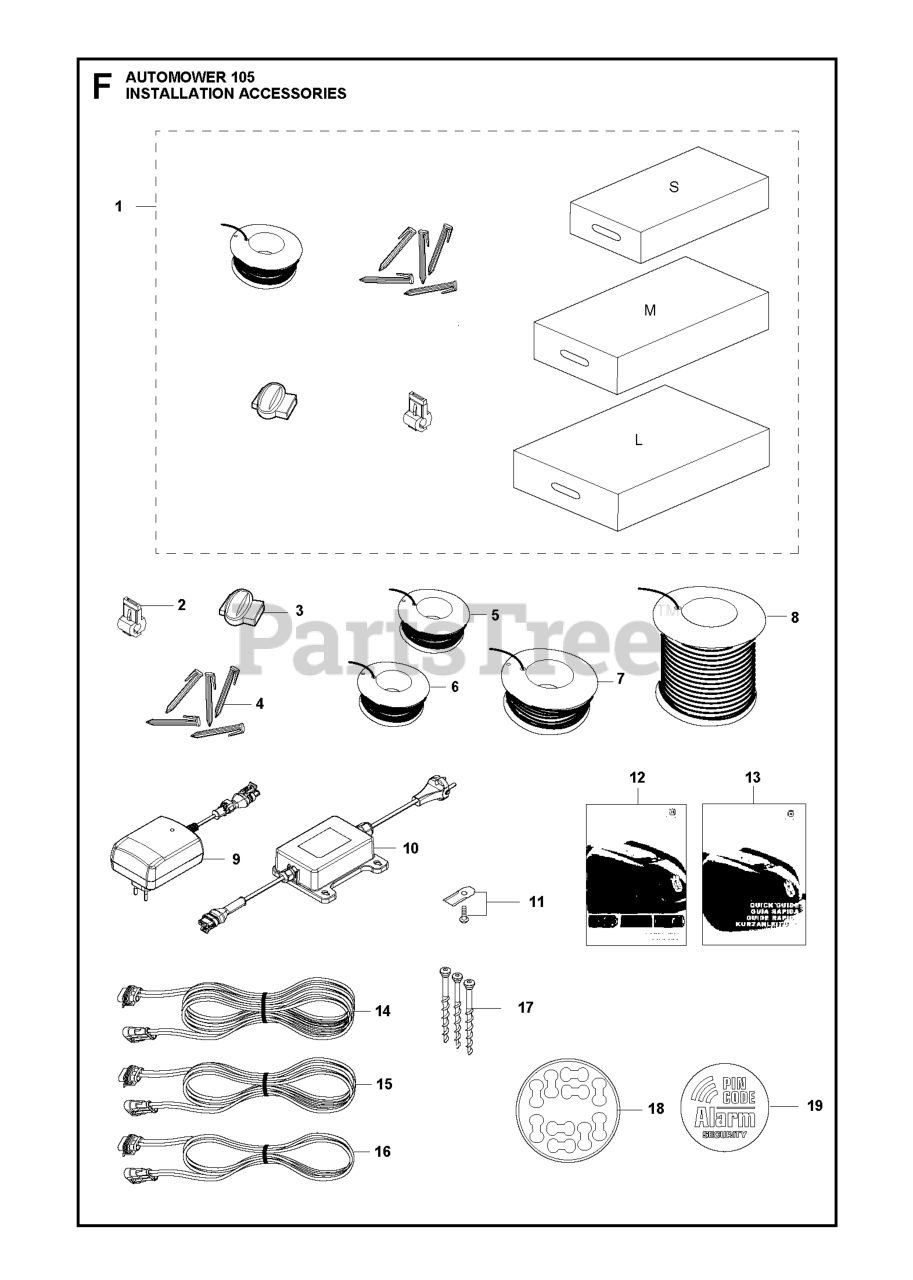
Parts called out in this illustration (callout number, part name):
1	LARGE AUTOMOWER INSTALL KIT
1	SMALL AUTOMOWER INSTALL KIT
1	MED AUTOMOWER INSTALL KIT
2	CONNECTOR 5 PCS, BLISTER
2	BRAKER
3	SPLICE KIT
3	COUPLER SPLICER, 5 PCS,
3	COUPLER SPLICER, 100 PCS
4	STAPLE 100 PCS, BLISTER
4	STAPLE 100 PCS
5	WIRE BOUNDARY 150M
5	WIRE 50M STANDARD Ø2.7MM,BLIST
5	WIRE 150M, BLISTER
7	WIRE 250M
8	WIRE (800M)
9	POWER UNIT POWER SUPPLY 1,3A
11	HUS BLADE SET 9 PCS
11	HUS BLADE SET 300 PCS
11	HUS BLADE SET 45 PCS
14	CABLE ASSY LOW VOLTAGE CABLE
15	CABLE ASSY LOW VOLTAGE CABLE
16	CABLE ASSY LOW VOLTAGE CABLE
17	SCREW 3 PCS, BLISTER PACK
17	SCREW KIT KIT INCLUDES THREE S
18	STICKER CABLE MARKERS KIT 10PC
19	LABEL SECURITY
